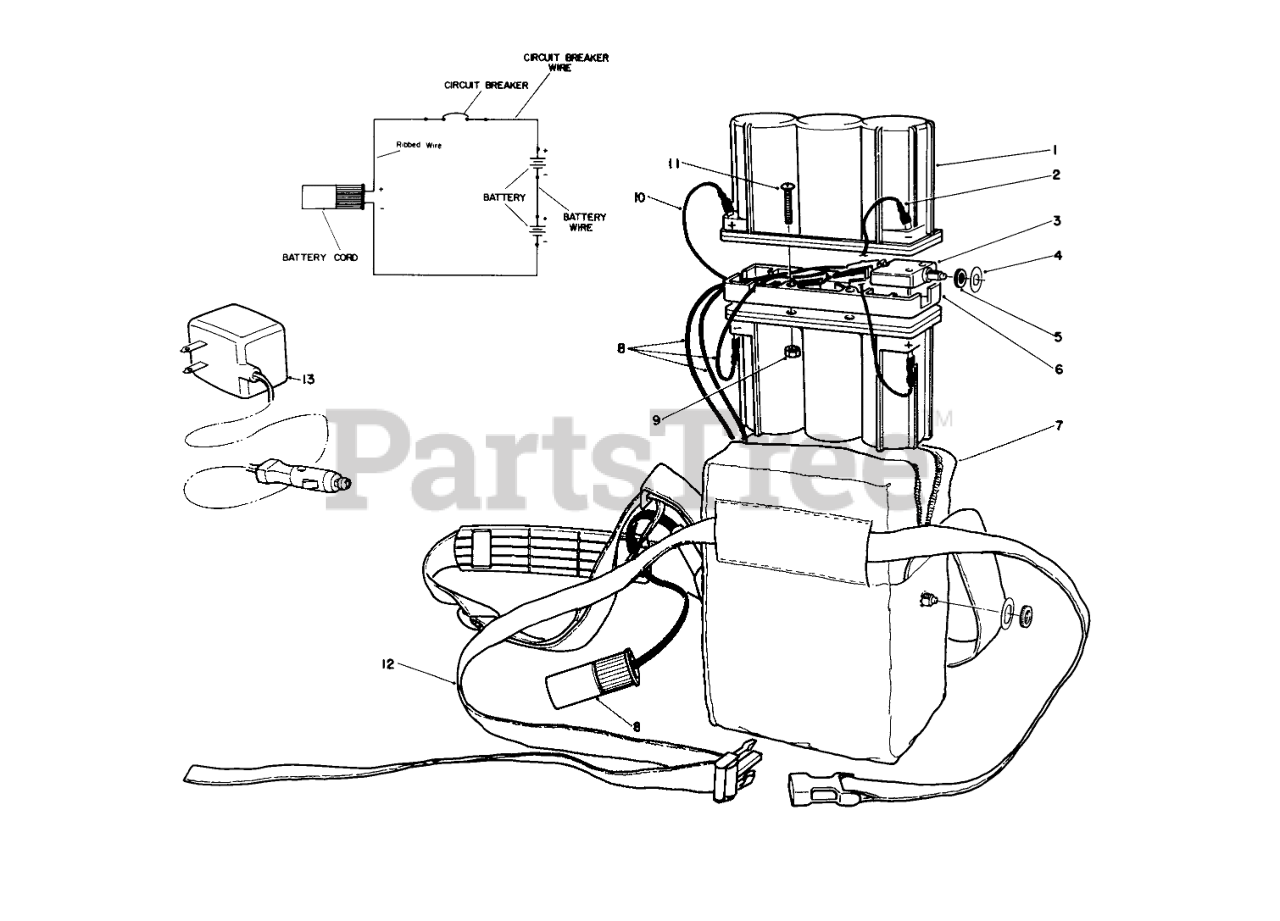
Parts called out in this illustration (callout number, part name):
1	BATTERY, 6 VOLT
2	WIRE ASSEMBLY-BATTERY
3	CKT BREAKER 15 AMP 125V
4	CIRCUIT BREAKER PLATE
5	KNURLED NUT
6	BATTERY SPACER
7	Pack-Soft
8	CORD-BATTERY PACK
9	NUT-HEX
10	WIRE ASSY-CIRCUIT BREAK
11	SCREW-PPH
12	BELT-WAIST
13	Charger 12 Volt
